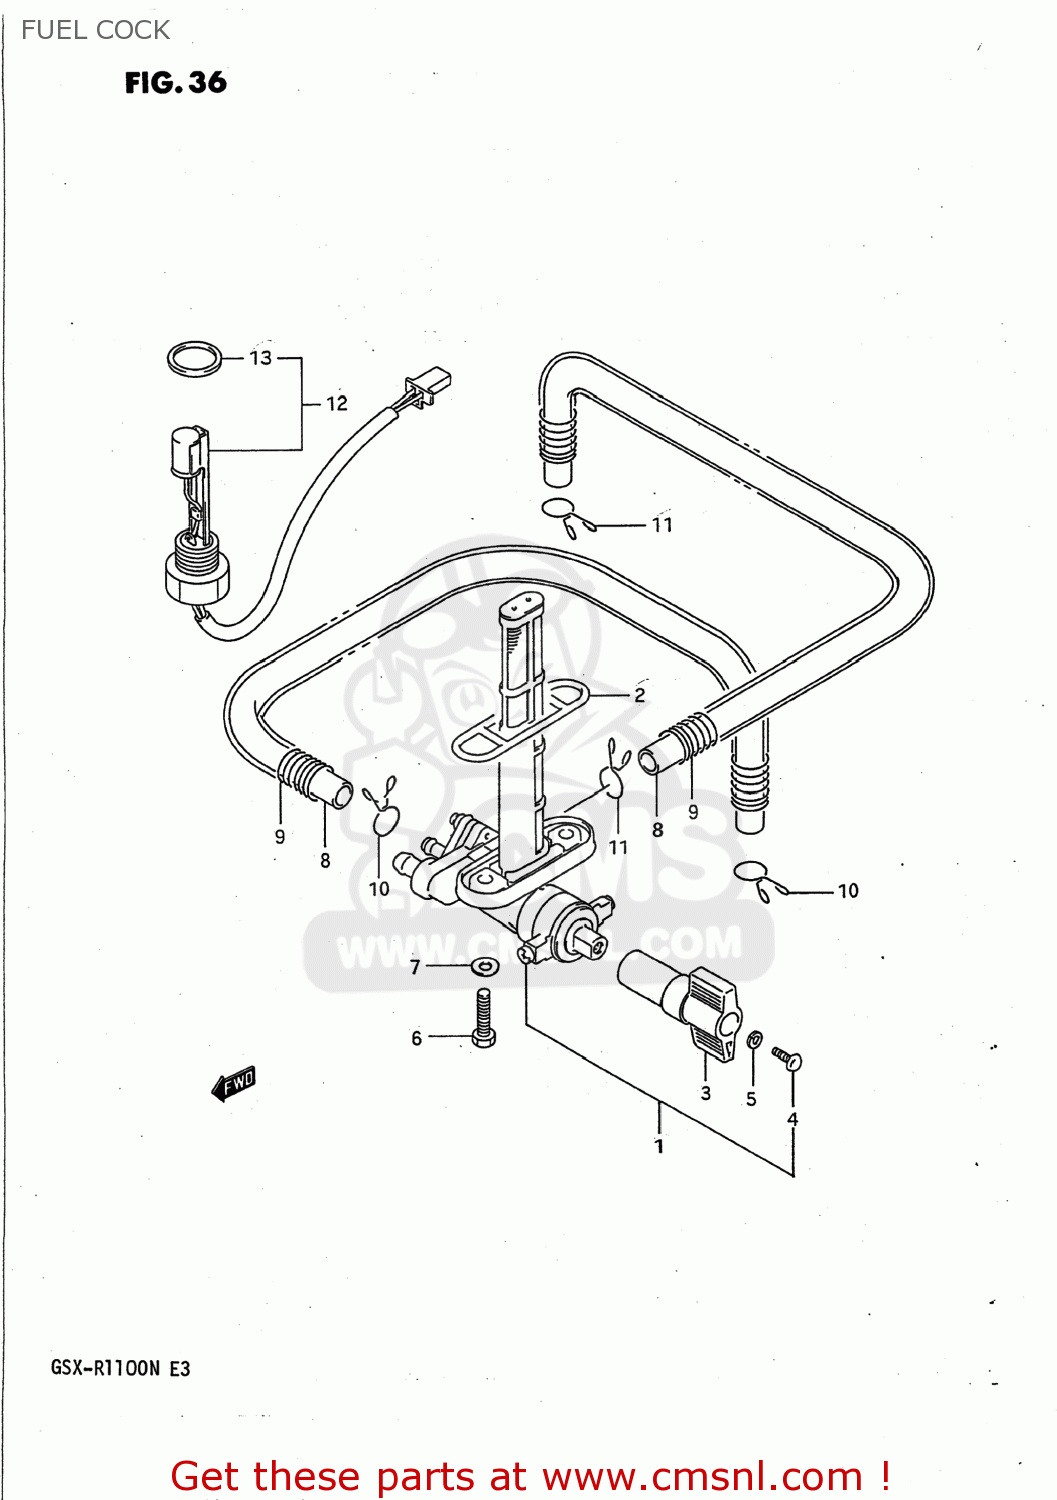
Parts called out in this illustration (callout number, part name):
1	COCK ASSEMBLY,FUEL
2	O RING,FUEL TANK JOINT
3	LEVER,FUEL COCK
4	SCREW
5	LOCK WASHER
6	BOLT(6X20)
7	GASKET(6.4X11.5X0.8) (NAS)
8	HOSE
9	SPRING
10	CLIP
11	CLIP
12	GAUGE ASSEMBLY,FUEL LEVEL
13	GASKET,FUEL LEVEL GAUGE (NAS)
